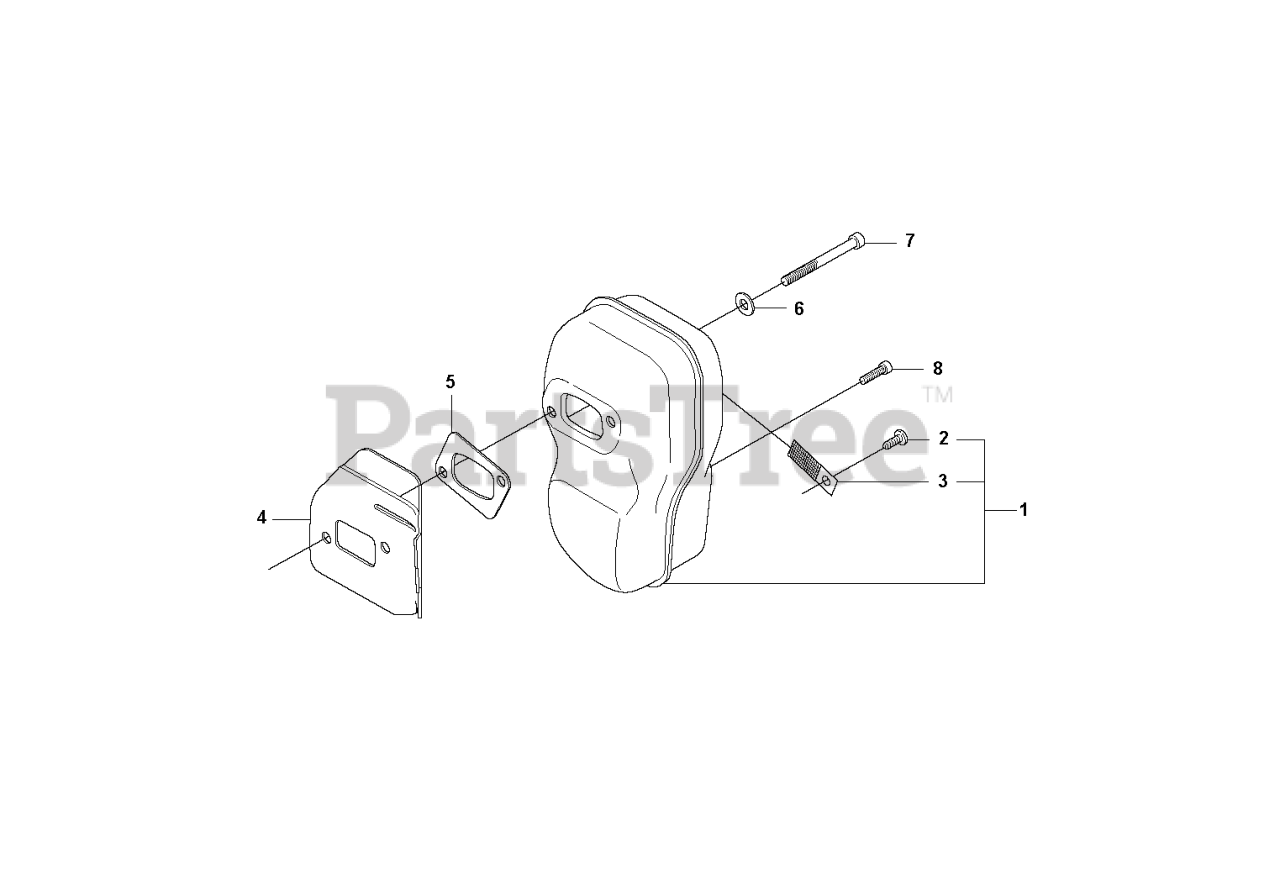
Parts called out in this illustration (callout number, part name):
2	SCREW
3	SCREEN
4	DEFLECTOR
6	DOUBLE WASHER
8	SCREW IHSCFM
